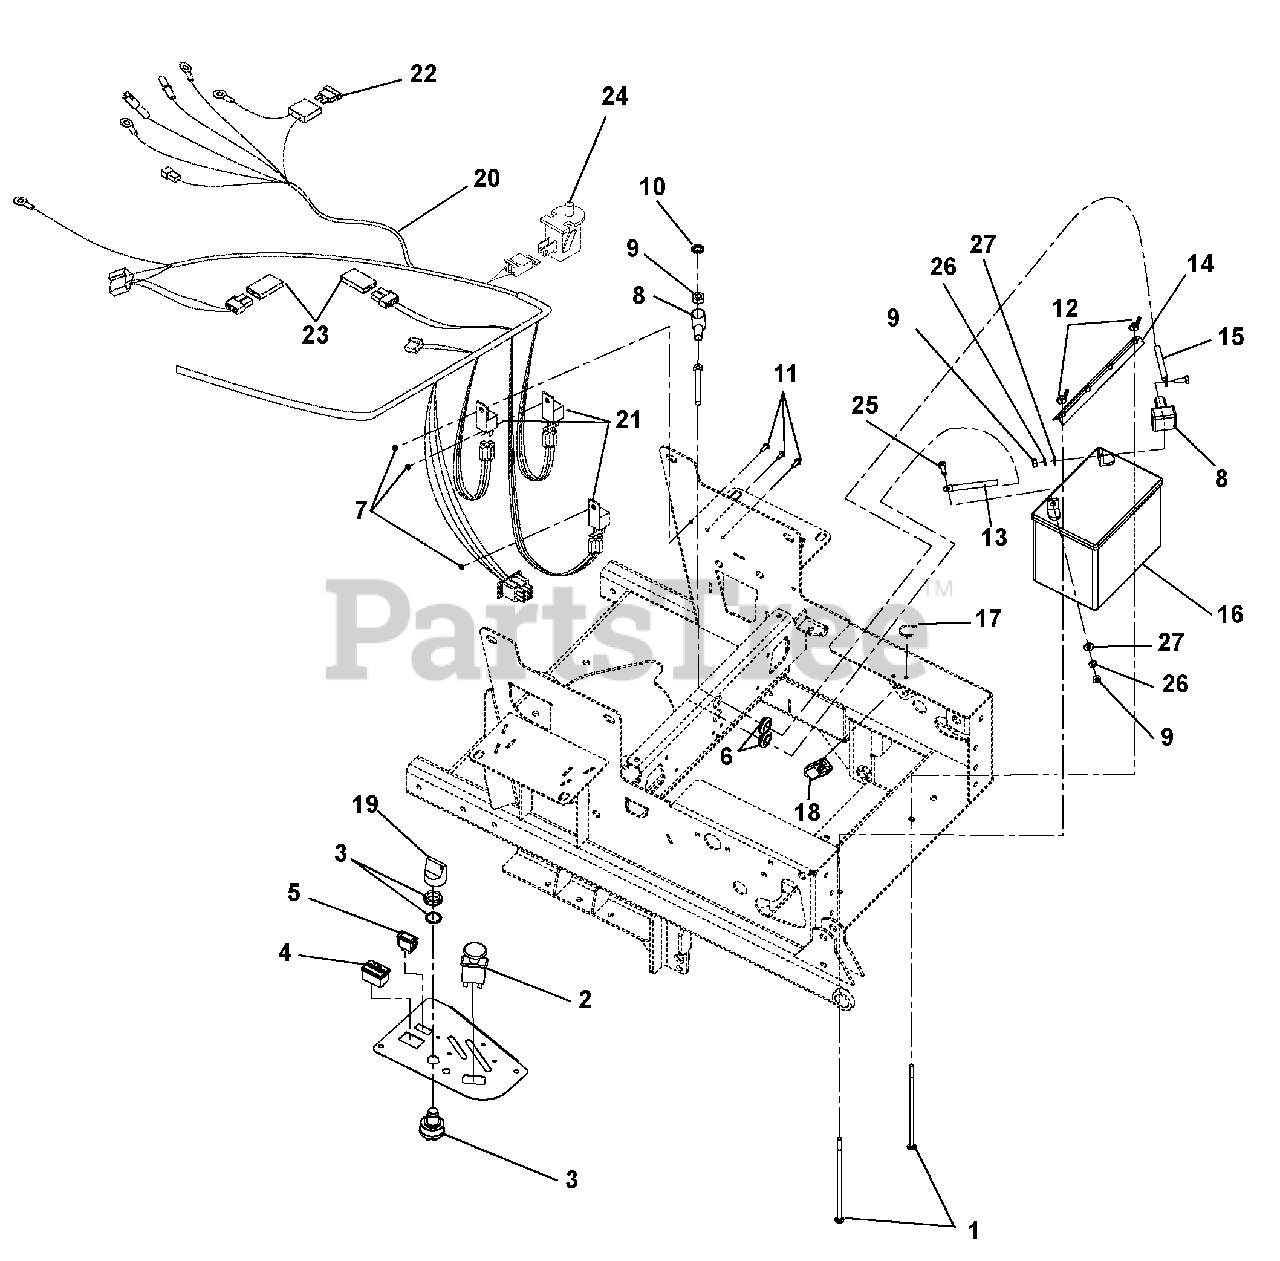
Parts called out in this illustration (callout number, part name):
1	BLT-RDHDSQNK .25-20X7.50 GR2YZ
2	SWITCH, CLUTCH
3	SWITCH, IGNITION
4	HOUR METER - DIGITAL
5	LIGHT,INDICATOR
6	GROMMET,RUBBER 5/8 ID/1.13 OD
7	NUT-LK-NYL 10-24 W/INSRT YWZC
8	BOOT, EYELET TERMINAL
9	NUT-HEX .25-20 YWZC
10	WSHR-LK-EXT.262X.502X.026YWZC
11	SCR-MCH 10-24X.50 HWH YWZC
12	NUT-LK WING .250-20 YWZC
13	GROUND CABLE .31X22.00X.31
14	HOLD DOWN
15	CABLE-POSITIVE BATTERY 26.00"
16	BATTERY, 300 CCA 10U1L
17	CABLE TIE LG 5-1/2
18	SWITCH, SNAP IN - N.O./N.O.
19	KEY, W/ SHIELD
20	HARNESS - IZ, CZ, 100I
21	RELAY,SEALED W/DIODE
22	FUSE, 30 AMP.
23	DIODE, CONNECTOR SHELL
24	SWITCH- SNAP MTG N.O.
25	BLT-HEX .25-20X.75 GR5 YWZC
26	WSHR-LK .25X.062 REG YWZC
27	WSHR-FL-STL.281X.62X.065 YWZC
